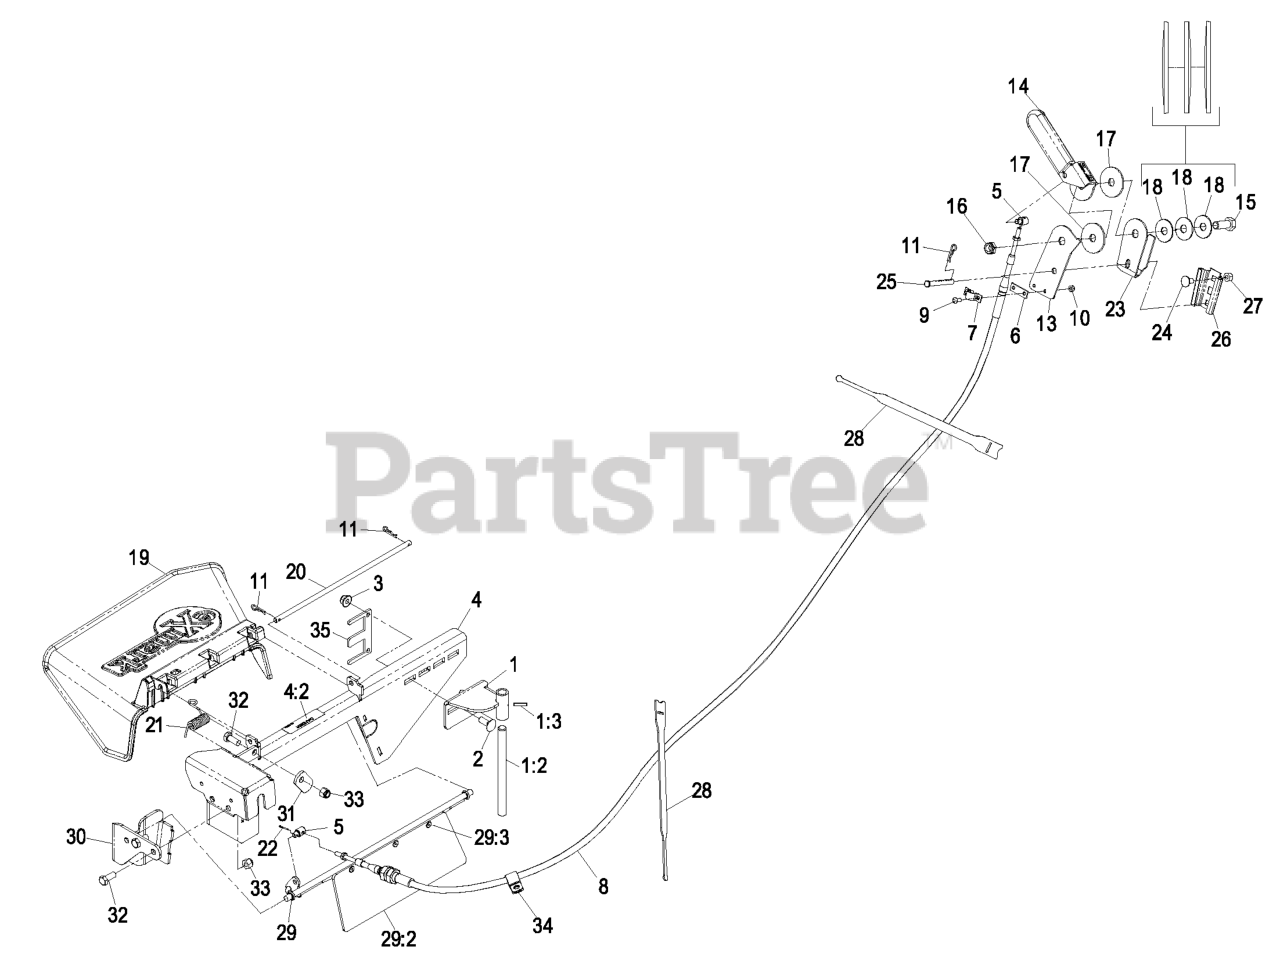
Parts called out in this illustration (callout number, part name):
1	ASM,OCD MOUNT
1:2	SHAFT-CATCHER, GRASS
1:3	PIN-ROLL
2	BOLT-CARR
3	NUT-HF, NI
4	GATE,LINK FRAME
4:2	DECAL-COVER, MISSING
5	PIVOT,CONTROL CABLE
6	SHIM,CONTROL CABLE
9	SCREW-PPH
10	NUT-LOCK, NI
11	PIN-COTTER
13	BRACKET,CONTROL MOUNT
14	CONTROL HANDLE ASM-OCD
15	SCREW-HH
16	NUT-HEX
17	DISC-FRICTION
18	WASHER-DISC, SPRING
19	CHUTE DEFLECTOR XRK M056
20	PIN,CHUTE
21	SPRING, TORSION
22	PIN-COTTER
23	BRACKET,HANDLE MOUNT
24	SCREW-CARR
25	PIN-CLEVIS
26	BRACKET-MOUNTING,SMV
27	NUT-LOCK, NI
28	STRAP-VELCRO, CABLE TIE
29:2	GATE,OCDCWB
29:3	RIVET-BLIND
30	BRKT,CHUTE FRONT
31	LATCH-CATCHER, GRASS
32	SCREW-HH
33	NUT-LOCK, NI
34	CLIP-LOOM
